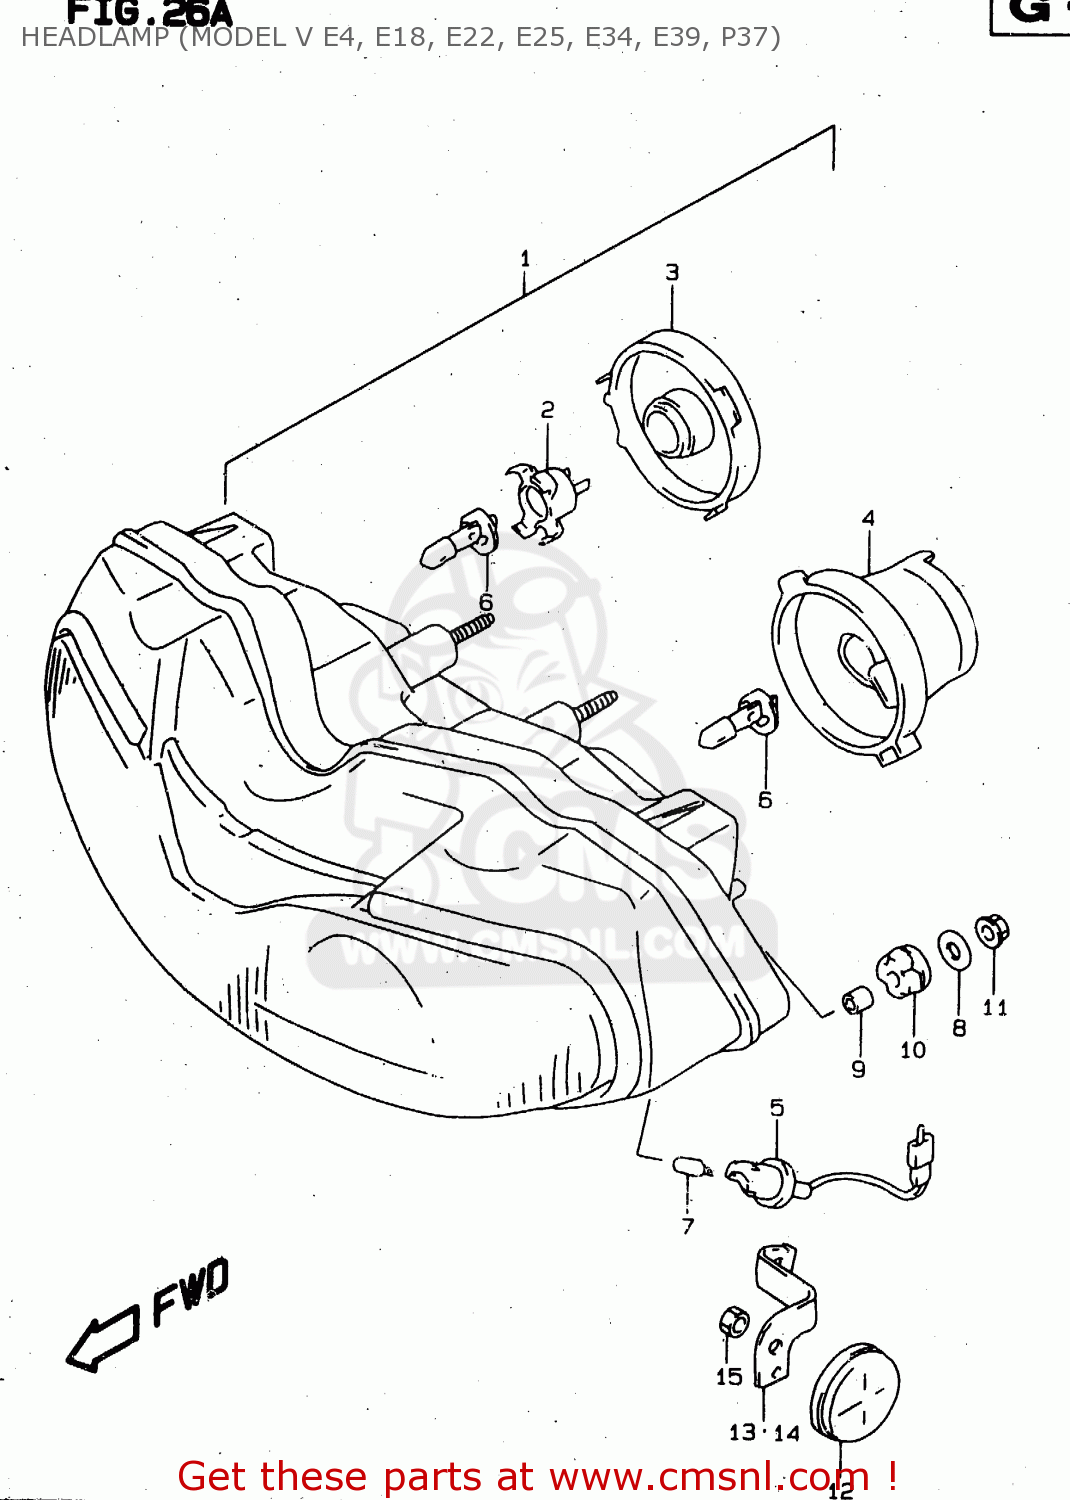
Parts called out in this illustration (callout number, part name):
1	HEADLAMP ASSY
2	ADAPTER ASSY
3	COVER,SOCKET
4	SOCKET & CORD ASSY
5	SOCKET ASSY
6	BULB(12V55W/H1/P14.5S/OSRA,PHI
7	BULB(12V5W)
8	WASHER(6.5X20X1.6)
9	SPACER(6.5X9X12.5)
10	CUSHION
11	NUT
12	REFLECTOR,REFLEX FR
13	BRACKET,FR SIDE RR,R
14	BRACKET,FR SIDE RR,L
15	NUT
